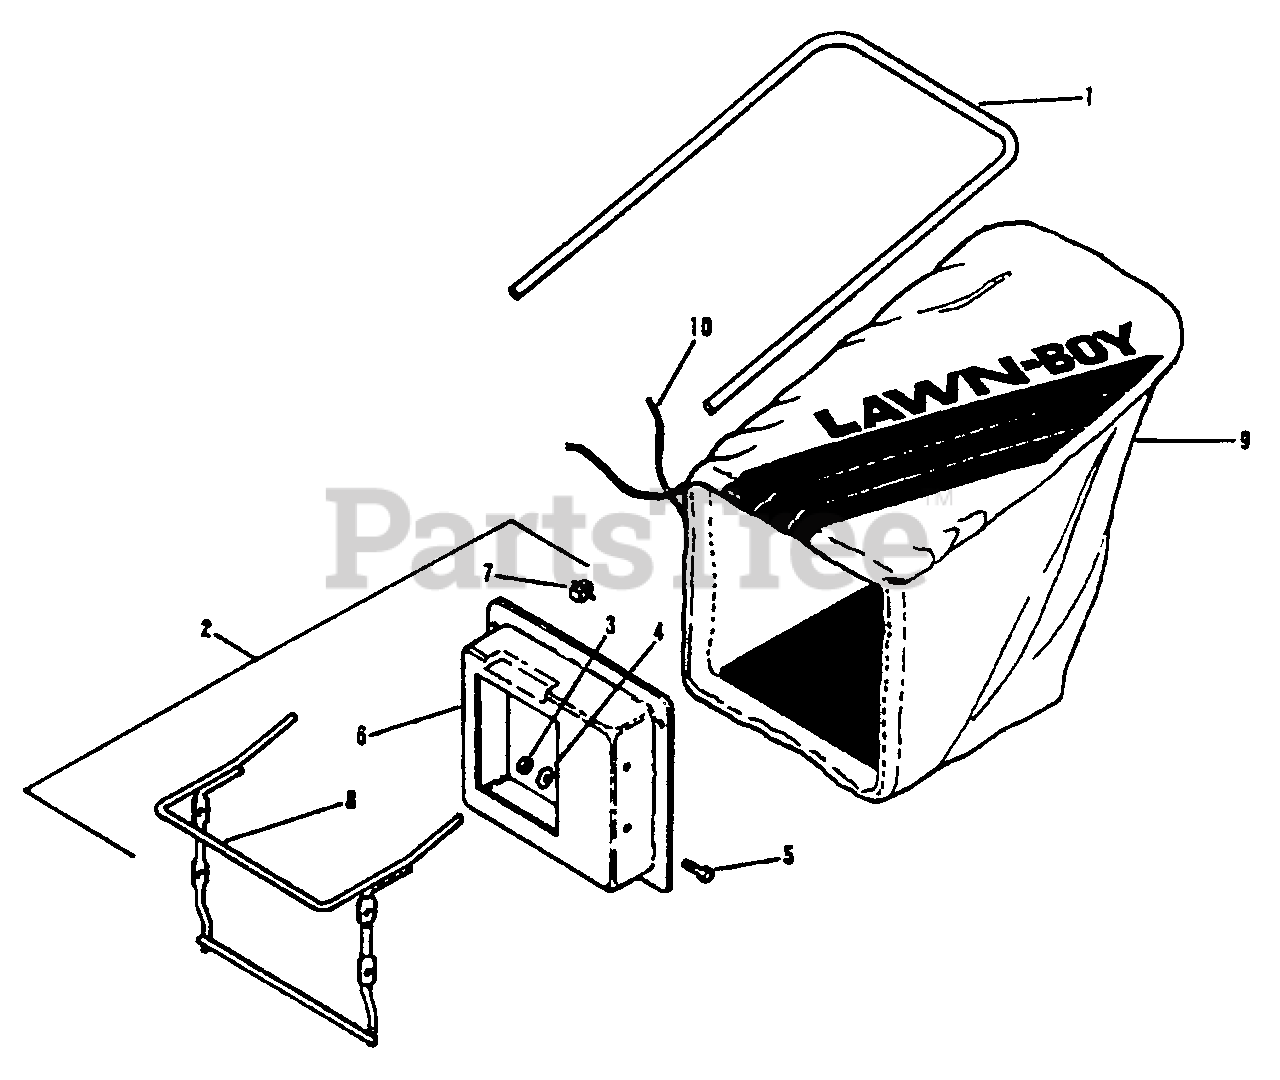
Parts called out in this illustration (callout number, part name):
1	Bag Hanger
2	Bag Adaptor Assy (Inc. 3-8)
3	Locknut
4	Flat Washer
5	Screw
6	Adaptor
7	"S" Clip
8	Latch-Bar
9	Replacement Bag Asy (Inc. 10)
